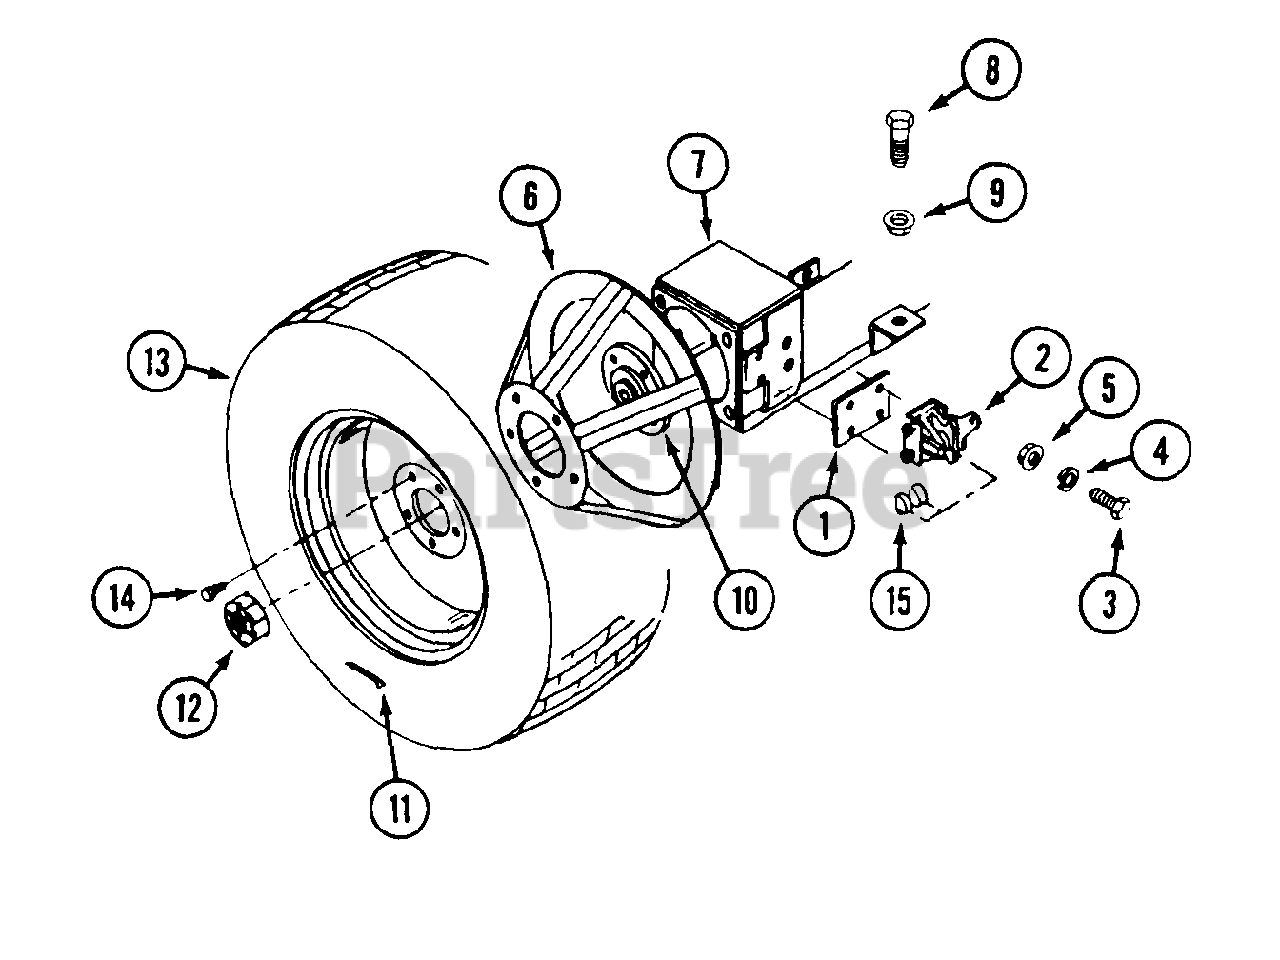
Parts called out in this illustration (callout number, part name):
1	MOUNT - caliper
2	BRAKE - caliper L.H.
3	BOLT - 5/16" - 18 x 3/4"
4	LOCKWASHER - 5/16"
5	NUT - 5/16" - 18 flange lock
7	AXLE - drive
8	BOLT - 1/2" - 13 x 1-1/4" (axle mounting)
9	NUT - 1/2" - 13 flange lock (axle mounting)
10	HUB - mounting
11	PIN - cotter 1/8" x 1-3/4"
13	WHEEL ASSEMBLY - 20 x 10-10
14	BOLT - lug 1/2" - 20 x 1"
15	PUCKS - brake (1 pair)
